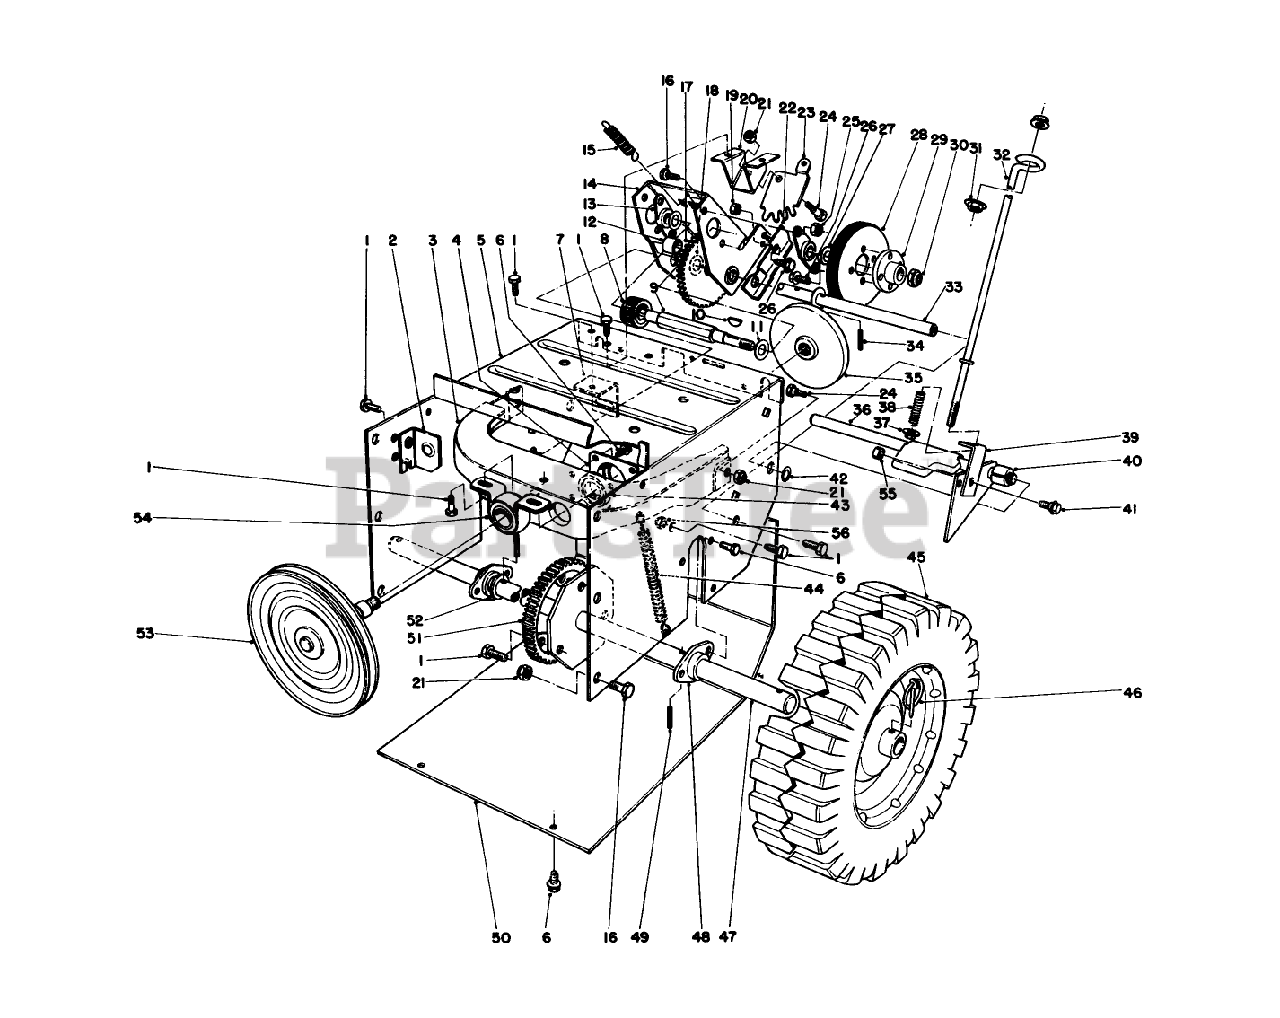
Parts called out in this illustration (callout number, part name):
1	SCREW-THD ROLL, HWH
3	FRICTION PLT FRAME
4	CUP-BEARING
6	SCREW
7	BRACKET-MOUNT, REAR
8	PINION
9	SHAFT-WHEEL, FRICTION
10	KEY-WOODRUFF
11	WASHER-FLAT
12	5/8ID X 1LG BUSHING
13	BEARING-WHEEL, FRICTION
14	BRACKET-SLIDING
15	SPRING-TRACTION
16	SCREW-HH
17	INTERNAL GEAR AND BUSHING ASM
18	WASHER-SPECIAL
19	NUT-LOCK, NI
20	MOUNT-LEVER
21	NUT-LOCK, NI
22	CAM-RECEIVER
23	GEAR-QUADRANT
24	BOLT-SHOULDER
25	NUT-LOCK, CONE
27	WASHER-THRUST
28	WHEEL-FRICTION
29	HUB-WHEEL, FRICTION
30	NUT-LOCK, NI
31	NUT-HF
32	ROD-TRACTION, LOWER
33	SHAFT-PIVOT
34	PIN-SPRING
35	PLATE-FRICTION
37	NUT-LOCK, HHF
38	SPRING
39	BRACKET-TRACTION
40	SPACER
41	SCREW
42	RING-RETAINING
43	BEARING-BALL
44	SPRING-PLATE, FRICTION
46	PIN-LYNCH
47	AXLE SHAFT WA
48	BEARING-AXLE
49	PIN-SPRING
51	GEAR-AXLE
52	WASHER-THRUST
55	NUT-LOCK, NI
56	NUT-ACORN
